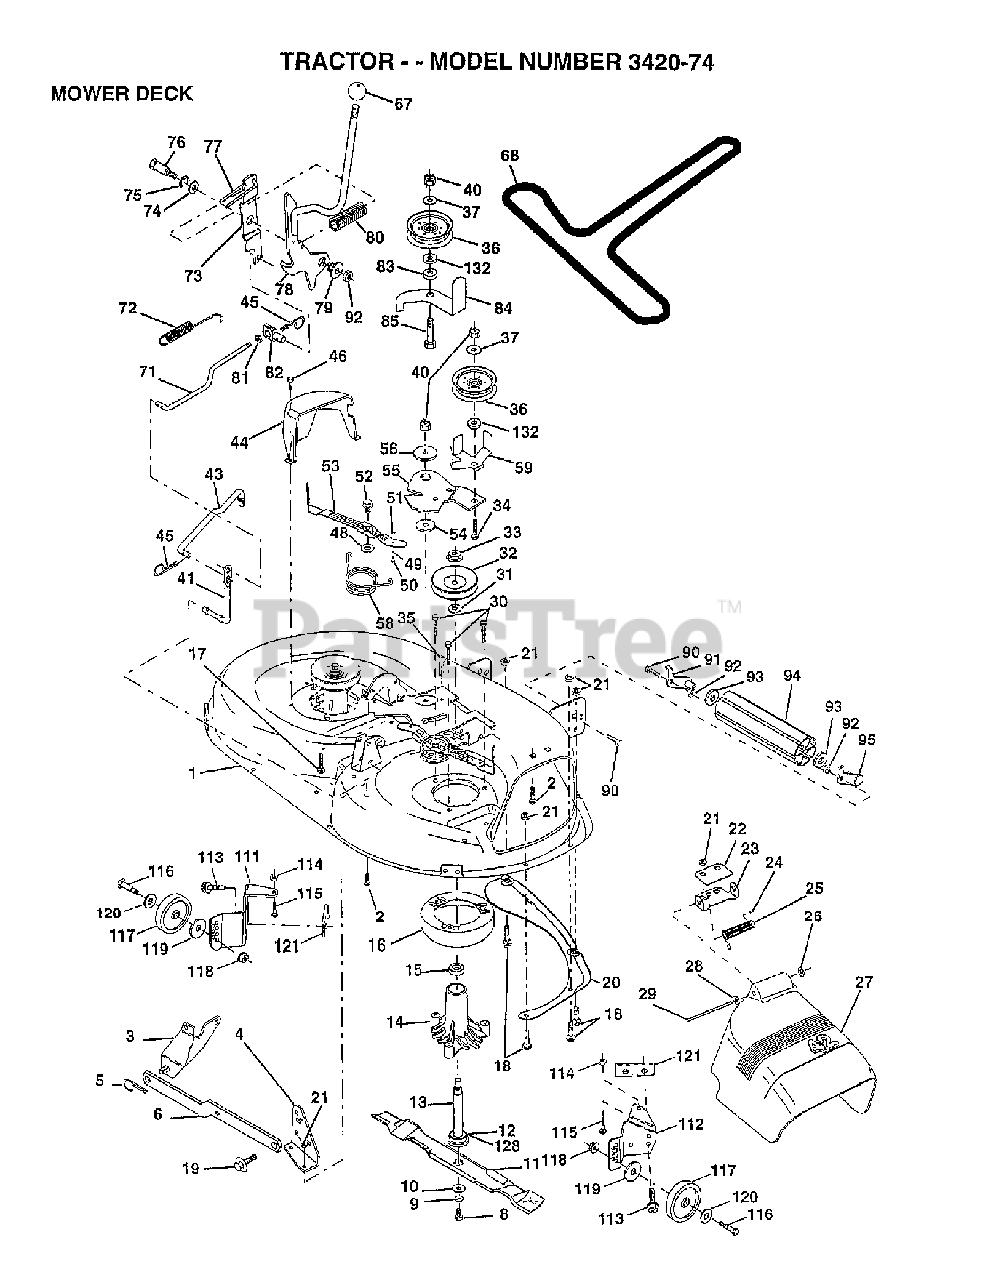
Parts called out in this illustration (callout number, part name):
2	BOLT
3	BRKT ASM SWAY BAR
4	BRKT DECK SW BAR
5	RETAINER SPRING
8	BLADE BOLT
10	WASHER.BLADE
11	BLADE 42" LOW-LIFT VENT DECK
12	BEARING.BALL.#6204.(MANDREL)
13	SHAFT ASM VENT
14	HSG MANDREL
17	BOLT
18	BOLT
19	BOLT SHD 5/16-18
21	LOCKNUT
23	DEFLECTOR BRACKET
24	CAP-SLEEVE LT
25	DEFLECTOR SPRG T
26	NUT PUSH M
27	SHIELD.DEFLECTOR.MOWER.42".BLK
28	WASHER
29	ROD.HINGE
30	Hex Washer Head Bolt, .313-18 X 1.19
31	WASHER
32	PULLEY/MANDREL
34	BOLT
35	FASTENER.XMAS.TREE
36	IDLER-FLAT GT
40	LOCKNUT
41	PIVOT ROD
43	CLUTCH ROD
44	MANDREL GUARD LH
45	RETAINER M
46	SCREW.1/4-20X5/8
50	BOLT
52	BOLT, SHOULDER LT
55	ARM IDLER 42" MOWER LT/YT
59	GUARD, BELT
67	PIGTAIL, LIGHT
68	V-BELT TRIPATH
72	RETURN SPRING
73	ARM CLUTCH SECONDARY
75	RING CLIP
79	BUSHING.FLANGE.E-RING.GROOVE
80	SPRING-CLUTCH
81	NUT
82	TRUNION T
84	KEEPER.BELT.IDLER
90	BOLT
91	Roller Bracket Assembly, LH
92	NUT
94	MANUAL, OPERATOR
113	Screw, Lt
116	BOLT
117	GUAGE WHEEL GT
118	LOCKNUT
119	WASHER
121	BRACKET.EXTRUDED.GAGE.WHEEL
128	WASHER FELT
132	WASHER GT
